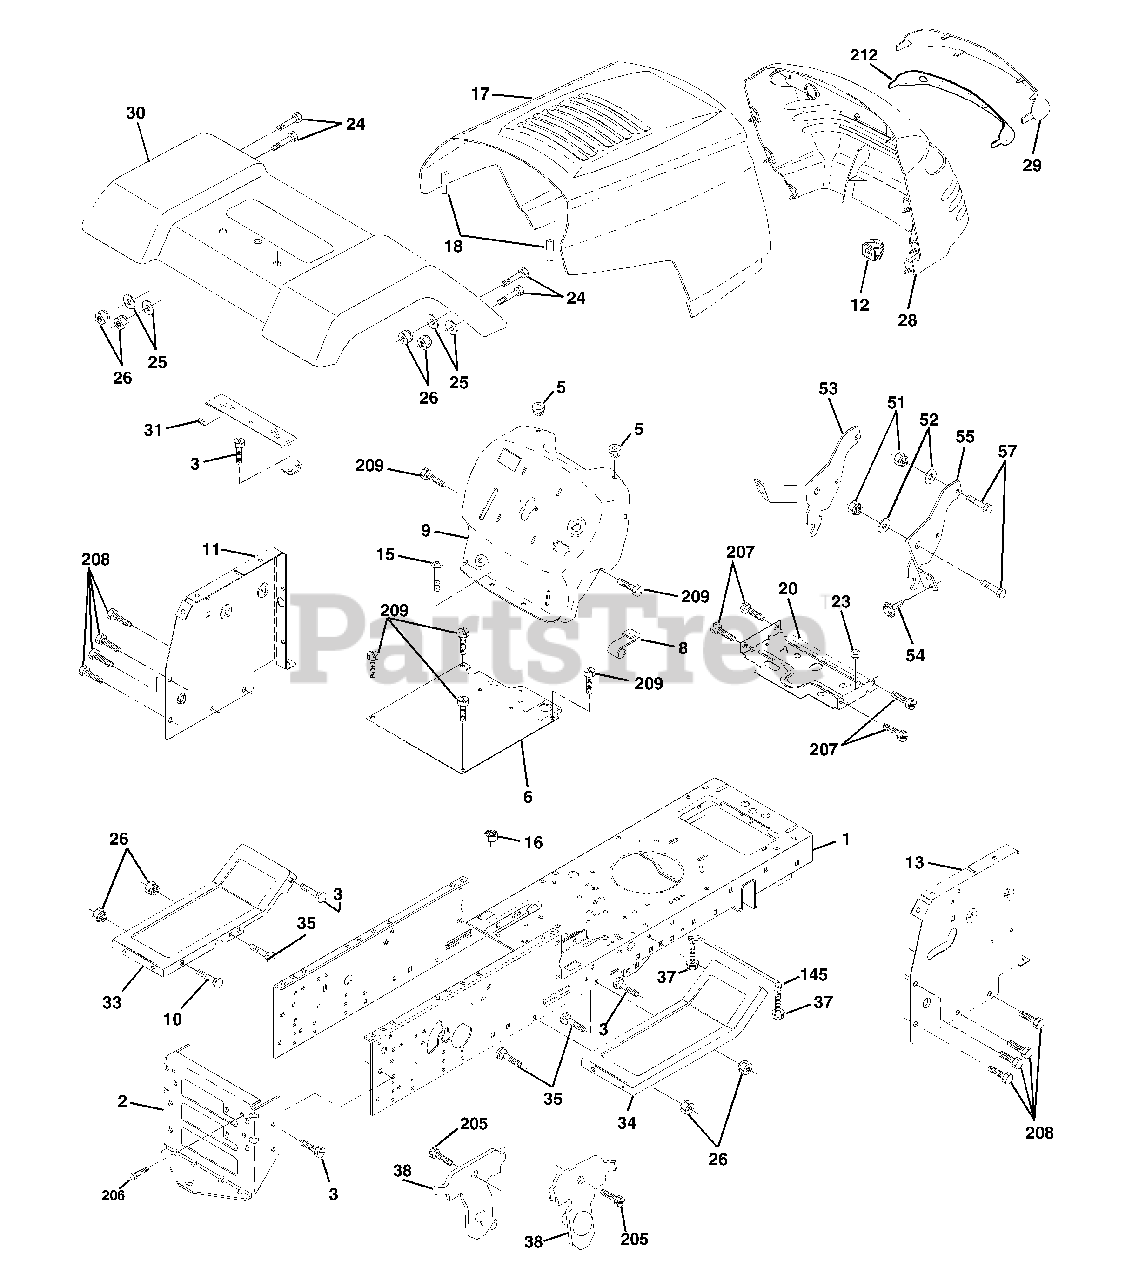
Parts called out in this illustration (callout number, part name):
1	Chassis
2	Drawbar
3	Screw 3/8-16 x 3/4
5	Bumper Hood/Dash
6	Saddle Flat Lt Fender Shift
8	Clip Retainer Slide-On
9	Dash
10	Bolt Rd Hd Sqnk. 3/8-16 Unc x 1
11	Panel Asm. Dash Lh
12	Clip Tinnerman Grile P/L
15	Screw Mach Trhd 5/16-18 Unc x 3/4
16	Nut Keps 5/16-18 Unc
17	Hood
18	Bumper Hood
20	Plate Mtg Battery/Fuel Tank Fr
23	Bushing Snap Nyl Blk Fuel Line
24	Bolt Fin Hex 3/8-16 Unc x 1 Gr. 5
25	Washer 13/32 x 13/16 x 12 Ga.
26	Nut Lock Hex w/Insert 3/8-16 UNC
28	Grill/Lens Asm
29	Lens Quadra
30	Fender Asm
31	Bracket Fender
33	Footrest Lh
34	Footrest Rh
35	Bolt Rd Hd Sht. Sqnk. 3/8-16 x 3/4
37	Screw Thdrol 5/16-18 x 1/2 Tyt
38	Bracket Asm. Pivot Mower Rear
51	Nut Lock Hex W/Ins. 1/4-20
52	Washer 9/32 x 7/8 x 16 Ga.
53	Bracket Grille LH
54	Screw Hex Wshd 8-18 x 7/8
55	Bracket, Grille RH
57	Bolt Fin Hex 1/4-20 x .75
145	Rod Pivot Chassis/Hood
205	Screw Thdrol 3/8-16 x 1/2
206	Bolt shoulder 5/16-18
207	Screw Thdrol 5/16-18 x 1/2
208	Screw Thdrol 3/8-16 x 1/2
209	Screw Hex Wsh Thdrol 3/8-16
212	Insert Lens Reflector
